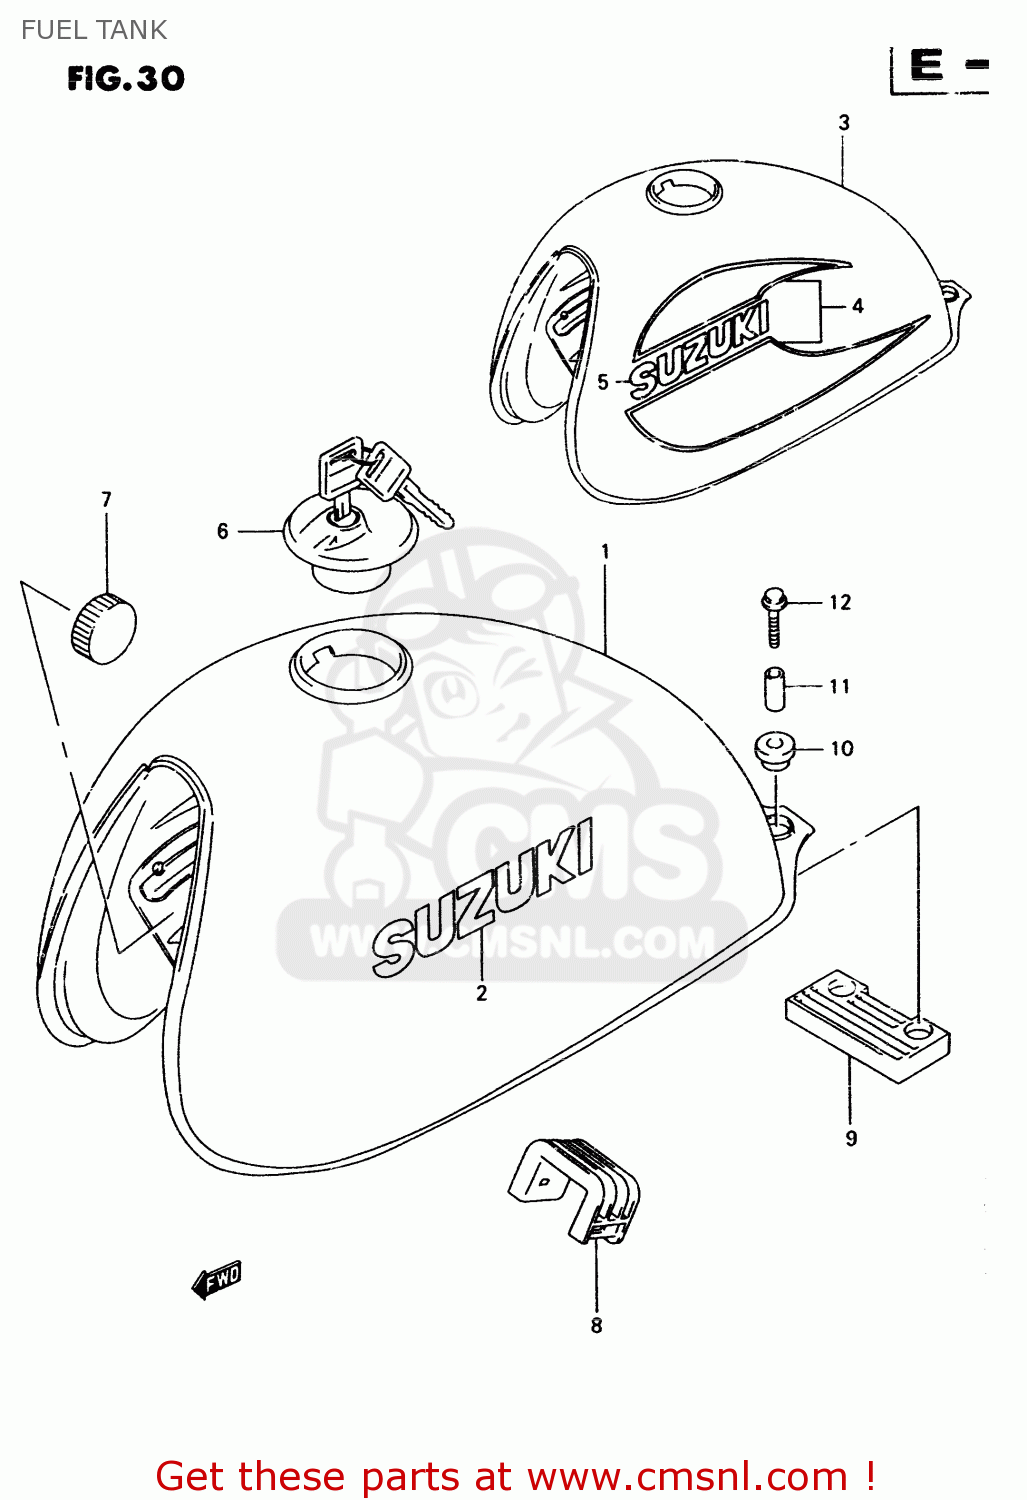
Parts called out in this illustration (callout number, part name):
1	TANK ASSY,FUEL
2	EMBLEM, FUEL TANK (GRAY)
3	TANK ASSY,FUEL(GREEN)
4	TAPE SET,FUEL TANK
5	EMBLEM, FUEL TANK (GOLD)
6	CAP SET,FL TAN
7	CUSHION
8	CUSHION,TANK UPR FR
9	CUSHION,TANK RR NO.1
10	CUSHION
11	SPACER(6.5X10.5X22.5)
12	BOLT
